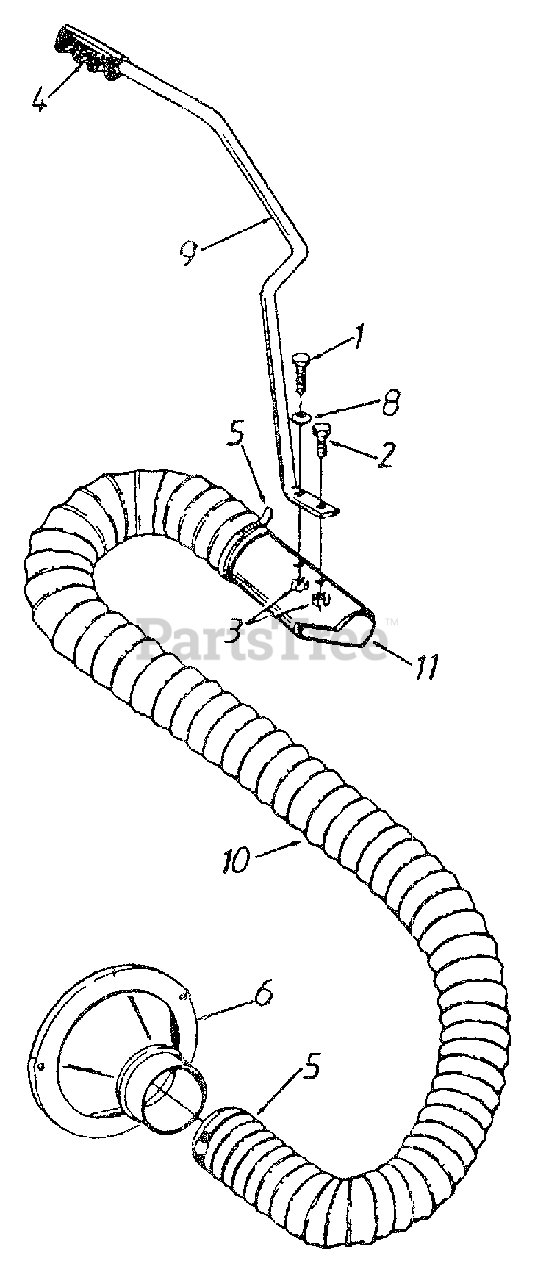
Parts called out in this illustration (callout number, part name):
1	Hex Bolt 1/4-20 x 1.25" Lg.
2	Hex Bolt 1/4-20 x .62" Lg.
3	Hex L-Nut 1/4-20 Thd.
5	Adj. Hose Clamp 5" Dia.
6	Hose Adapter
8	Saddle Washer .32" I.D.
10	Hose-5" Dia.
11	Nozzle Tube
